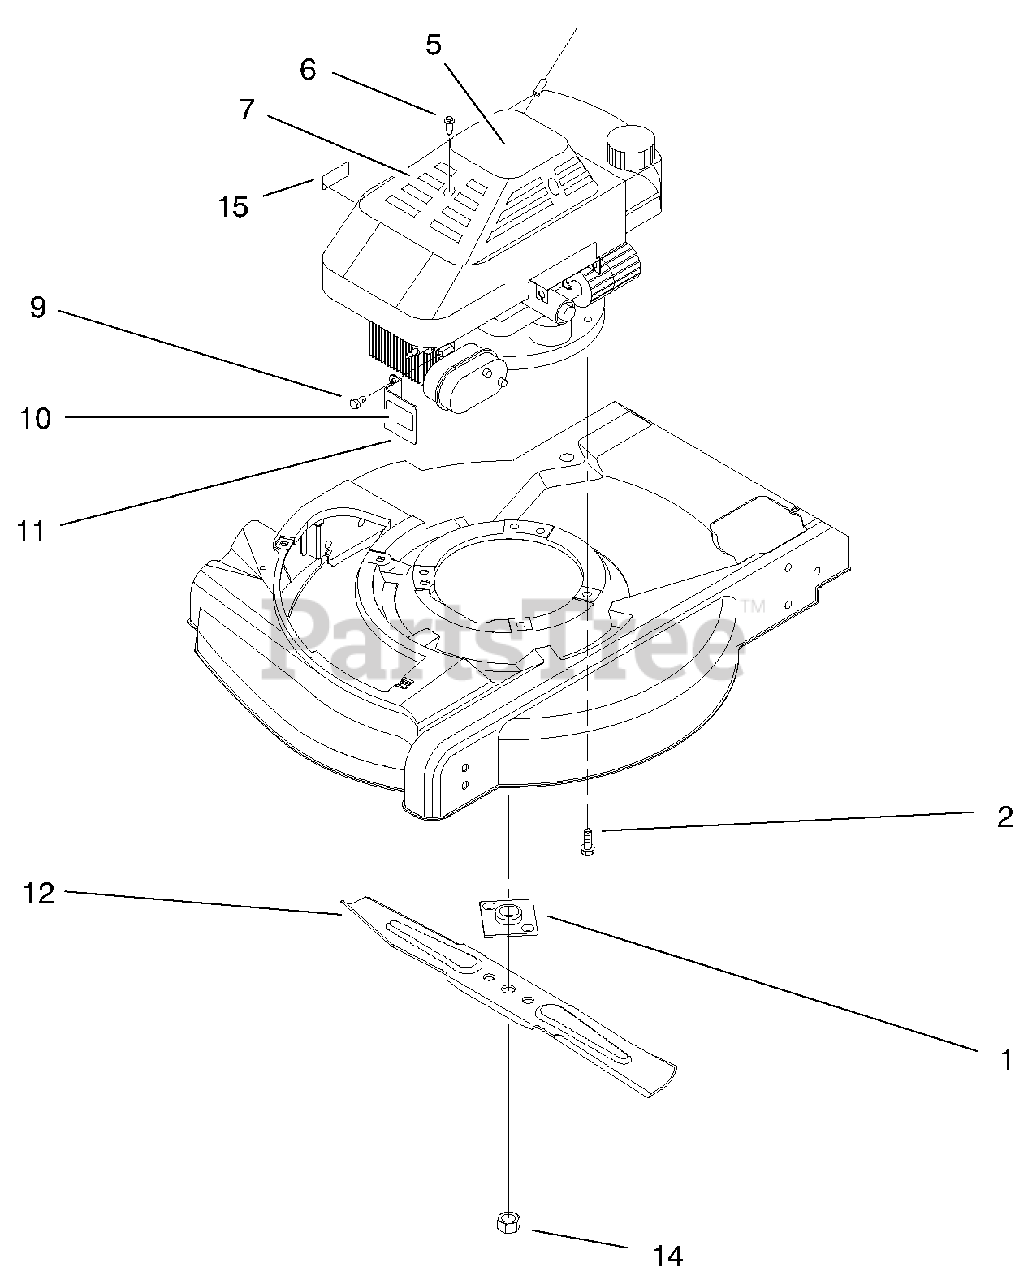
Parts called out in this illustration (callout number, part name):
1	Plate & Collar S
2	Screw-Taptite w/Patch
5	Decal-Recoil
6	Screw-Cover Recoil
7	Cover-Starter
9	Screw-TAP
10	Decal-Hot Surface
11	Guard-Muffler
12	Blade-21" Whirl
14	Nut-Blade
15	Decal-Oil Instr. F/W Eng
